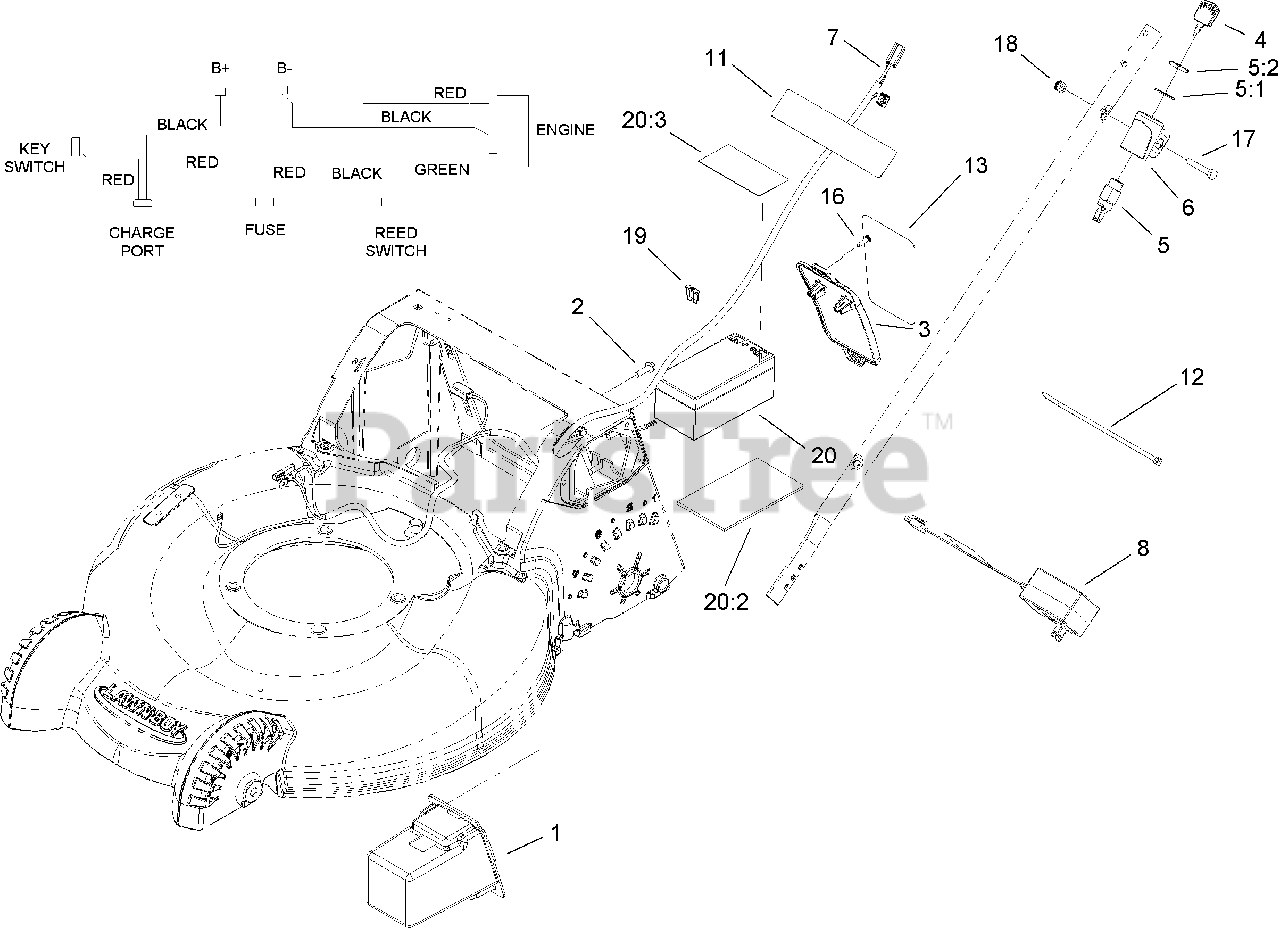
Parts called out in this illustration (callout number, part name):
1	BOX-BATTERY
2	SCREW-HWH
3	COVER-BATTERY
5	SWITCH-STARTER
5:1	WASHER-TOOTH
6	MOUNT-SWITCH
7	HARNESS-WIRE
8	CHARGER-12 VOLT
11	DECAL-HARNESS
12	STRAP-TIE
13	DECAL-INSTRUCTION, BATTERY
16	SCREW-PPH
17	SCREW-HH
18	NUT-LOCK, NI
19	FUSE-40 AMP
20:2	FOAM-BATTERY
20:3	DECAL-BATTERY TERMINAL
